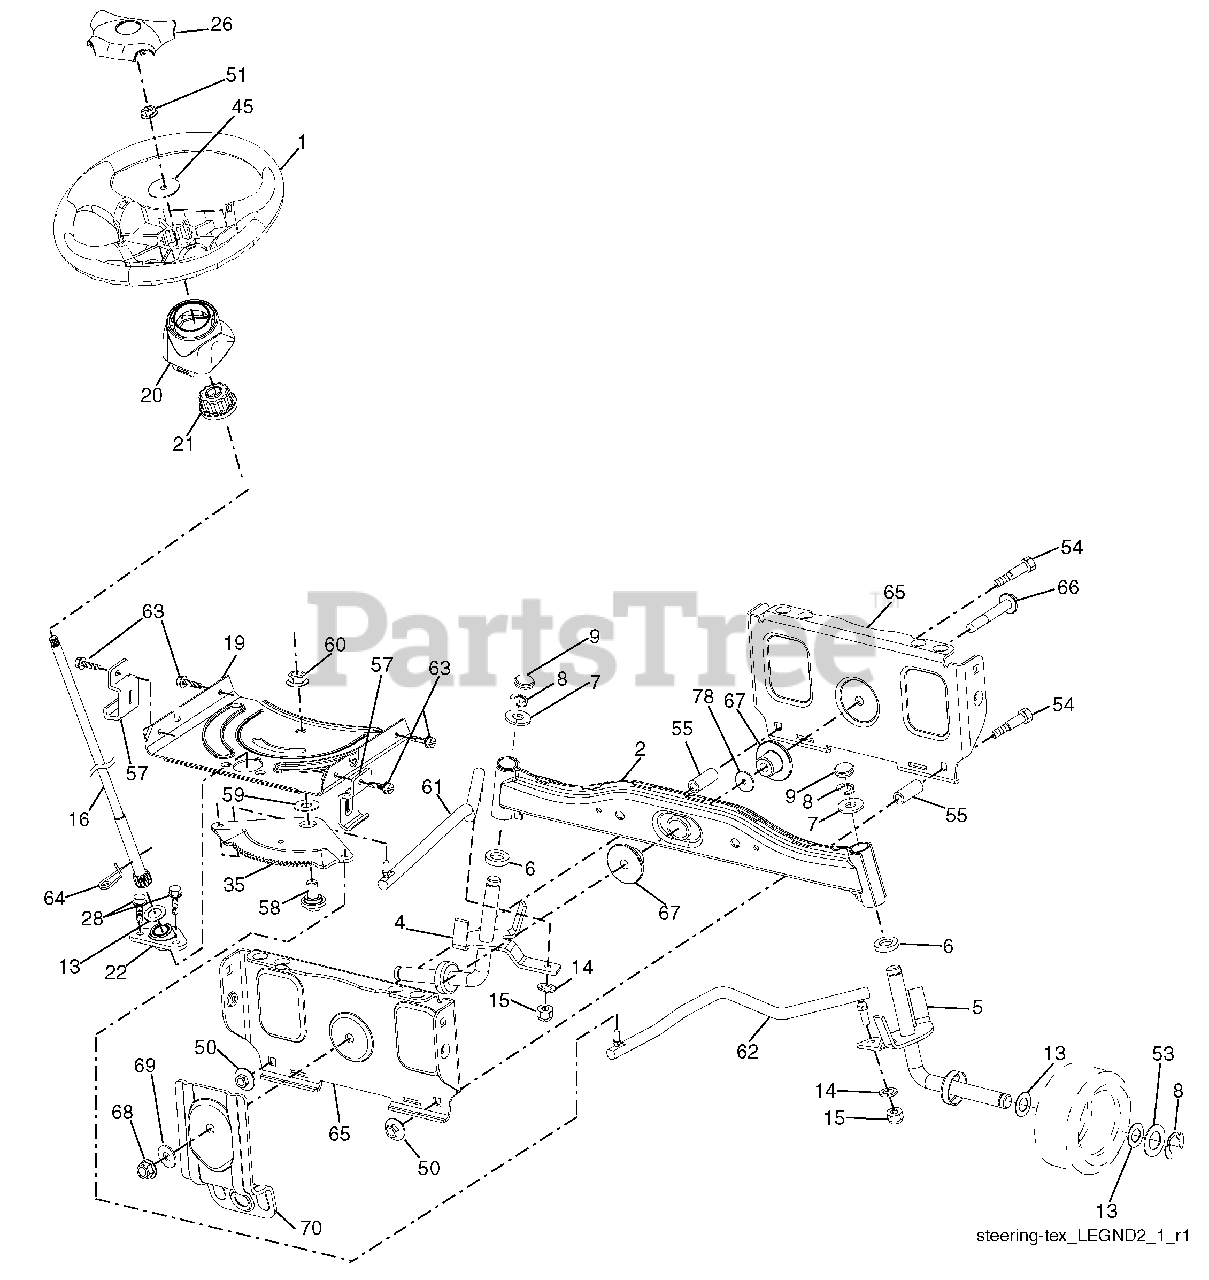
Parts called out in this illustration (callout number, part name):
1	Wheel, Steering
2	Axle Asm., Front
4	Spindle Asm., LH
5	Spindle Asm., RH
6	Bearing, Race Thrust Harden
7	Washer 25/32 x 1-5/8 x 16 Ga.
8	Ring, Clip #T5304-75
9	Cap, Spindle
13	Washer 25/32 x 1-1/4 x 16 Ga.
14	Washer, Lock Hvy Hlcl Spr 3/8
15	Nut, Crown Lock 3/8-24 unf
16	Shaft Steering
19	Plate Steering
20	Boot, Steering
21	Adapter, Wheel Steering
22	Bushing, Strg. Blk
26	Insert, Wheel Steering
28	Screw 3/8-16 x 3/4
35	Gear, Sector Plate
45	Washer 9/16 ID x 2-3/8 x 12 Ga.
50	Nut Lock 3/8-16 unc
51	Nut Hex Jam Toplock 1/2-20 unf
53	Washer Hardened .793 x 1.637 x .060
54	Bolt Hex 3/8-16 unc x 2-1/4
55	Spacer Brace Axle
57	Bracket Upstop
58	Bolt Shoulder Sector Pivot CFM
59	Washer Thrust Sector Steering
60	Nut Flange Lock 5/8-11
61	Draglink, LH
62	Draglink, RH
63	Screw 5/16-18 x 3/4
64	Retainer Clip Spring Steering
65	Brace Axle Front
66	Bolt Hex Fghd 7/16-14 x 3 Serr
67	Bushing PM Front Axle
68	Nut Lock Flange 7/16-14 Gr. 5
69	Washer 1.5 x .505 x .118
70	Bracket Deck Susp. Front
78	Washer Thrust .515 x .750 x .033
